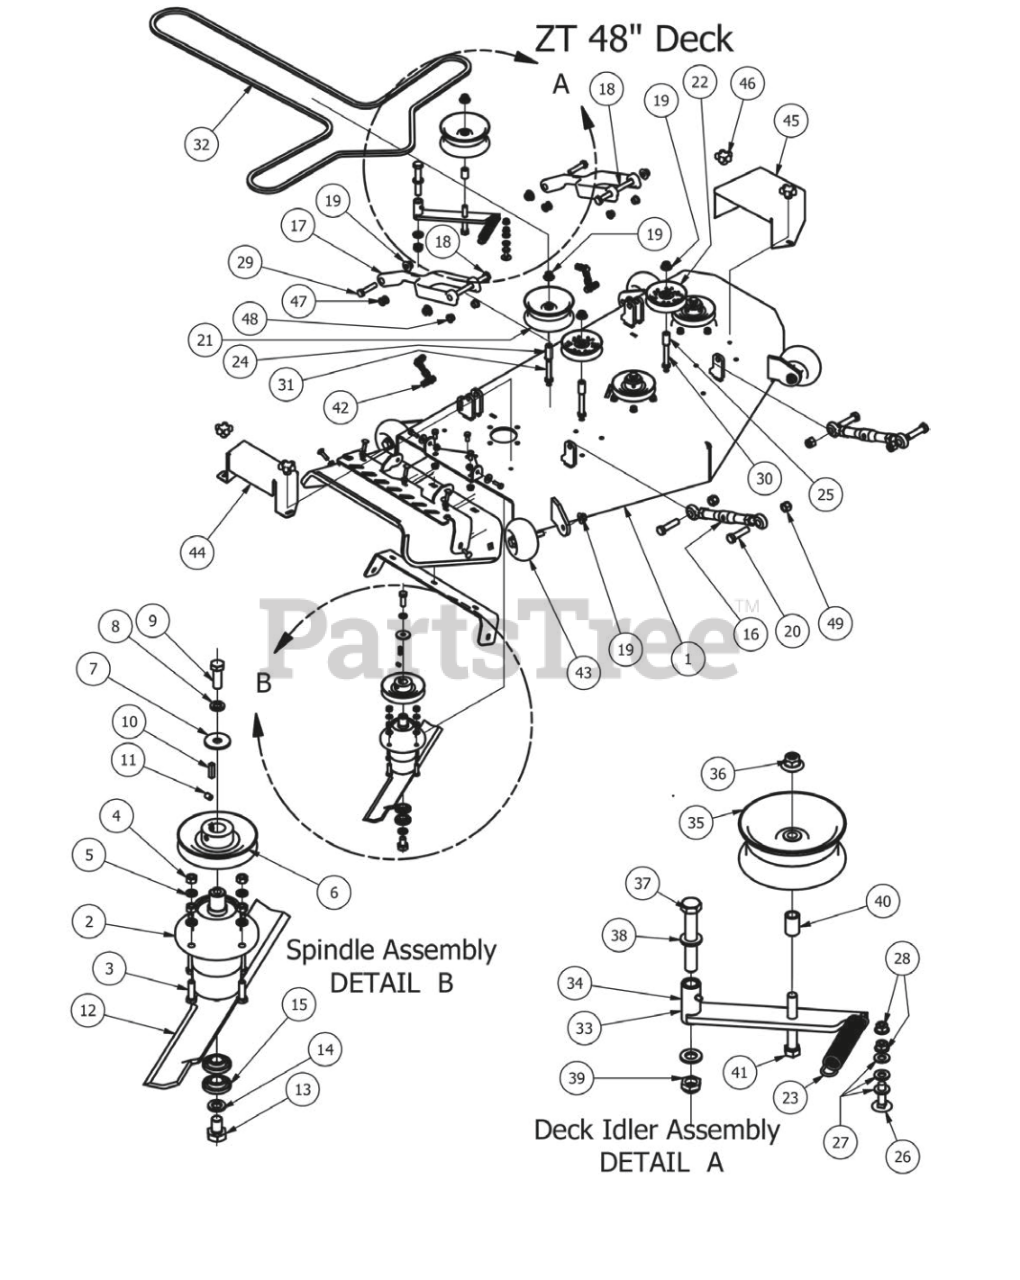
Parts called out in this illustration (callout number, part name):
1	48" Deck Only
2	Spindle - Aluminum - 2012 ZT
3	3/8" x 1 1/4" Hex Bolt
4	3/8" Hex Nut
5	3/8" Lock Washer
6	5" Deck Pulley
7	1/2 Belleville Washer
8	1/2" Lock Washer
9	1/2"-20 x 1 1/2 - Grade 5 Fine Thread Bolt
10	1/4" x 1" Key
11	3/8" Set Screw
12	50 Inch Fusion Blade
13	5/8" x 1 1/2" Grade 8 Bolt
14	5/8" Lock Washer
15	Spindle Bearing
16	Turnbuckle (Top Link)
17	Deck Arm Assembly
18	1/2" x 5 1/2" Bolt
19	1/2-13 Nylon Flange Nut-Orange
20	5/8" x 2 1/2" Hex Bolt
21	5 3/4" Deck Idler Pulley
22	4-3/4 Idler Pulley
23	Deck Idler Spring
24	1 3/4" Pulley Spacer
25	.502 ID X.75 OD X 1.500 Leng
26	3/8 x 1-1/2 Carriage Bolt
27	3/8" Flat Washer
28	3/8" Nylock Flange Nut
29	1/2-13X 2-1/4 GR Hex Bolts
30	1/2 x 3 1/2 Flange Bolt Grade 8
31	1/2" x 4" Bolt (Grade 8)
32	48" Deck Belt
33	Deck Idler Assembly 48" ZTComponents 34,35,36,40,41
34	Deck Idler Bracket
35	5 3/4" Deck Idler Pulley
36	1/2-13 Nylon Flange Nut-Orange
37	5/8" x 4" Hex Bolt
38	.635 ID Plastic Washer
39	5/8" Nylock (1/2 Jam)
40	.502 x .750 x 1.25 Length Spacer
41	1/2-13 x 3 1/2 GR 5 Hex Bolt
42	Chain assembly
43	Deck Wheel
44	1/2 Metal Spindle Cover
45	Pulley Cover
46	5/16" Knob
47	Flange for Lower Deck Arm
48	Flange Bushing For Deck Arm upper
49	5/8 Std NC Nylock Nut
